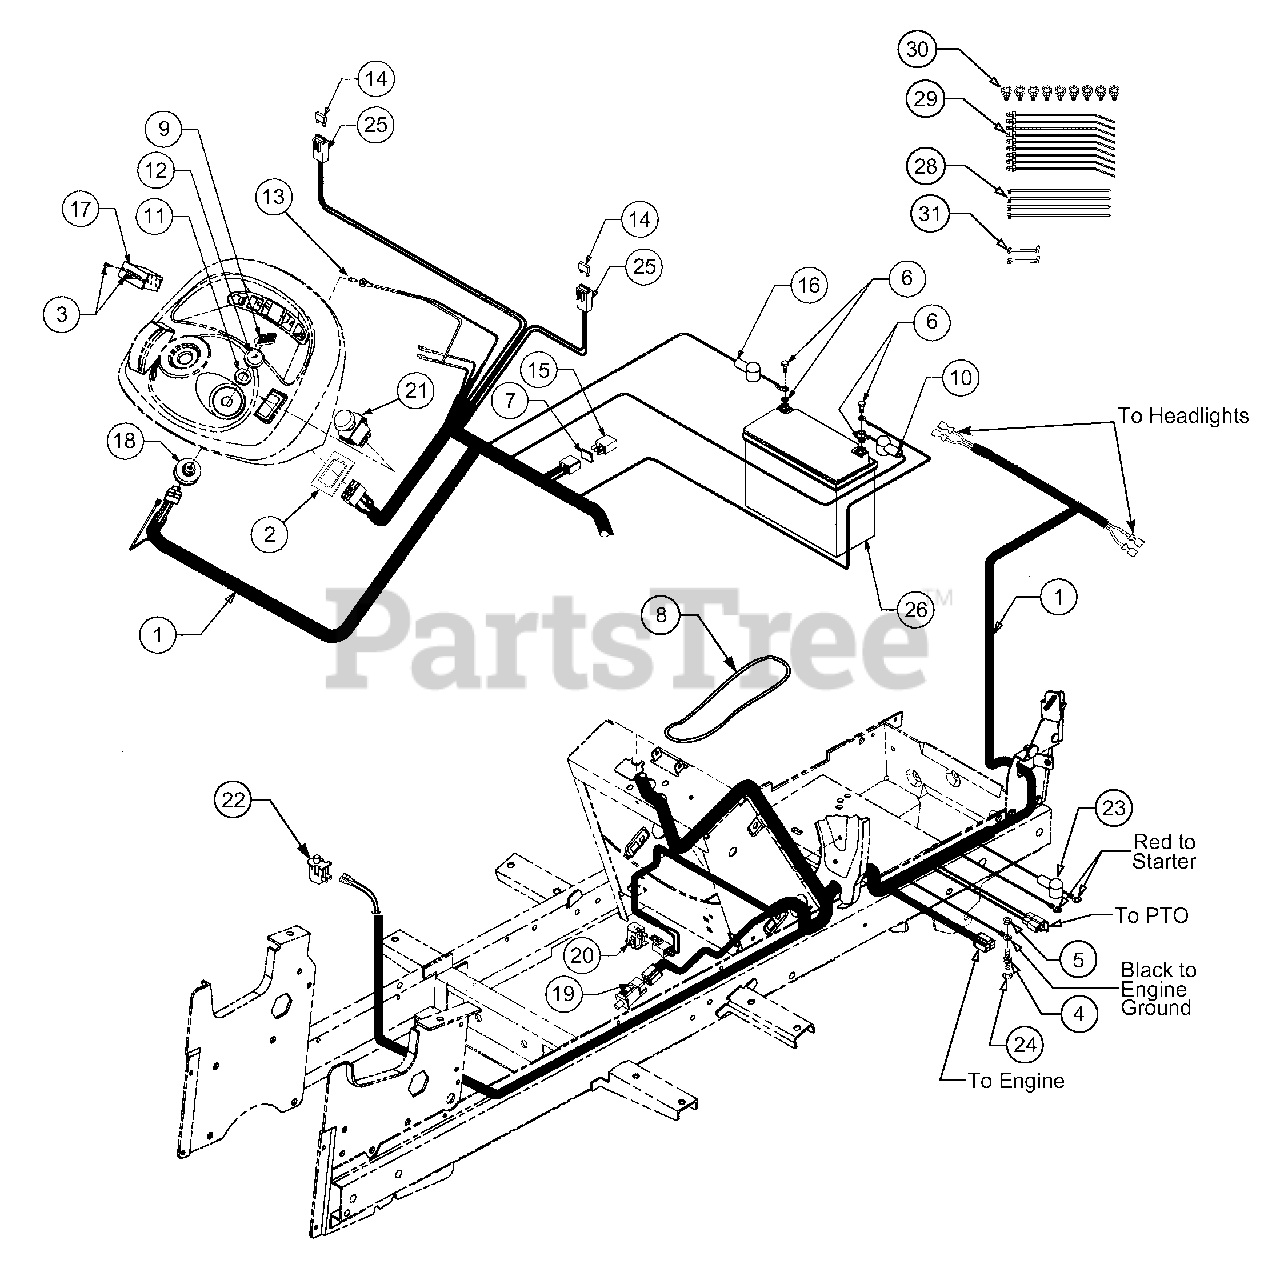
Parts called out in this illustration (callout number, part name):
1	Wire Harness, Main
2	Bracket, PTO Switch Retainer
3	Screw, Truss Hd Tapp, #6 x .62
4	Stud, Ground
5	Nut, Hex, 5/16-18 GR5
6	Battery Cable Hardware
7	Gasket, Silicone
8	Strap, Battery Retainer
9	Key, Ignition (Set of 2)
10	Cover, Terminal Black
11	Nut, Ignition Switch
12	Cap, Ignition Switch
13	Bulb, Indicator
14	Fuse, 25 Amp
15	Relay
16	Cover, Terminal Red
17	Hour Meter
18	Switch, Ignition
19	Switch, Interlock (Brake)
20	Switch, Snap Mount - Normally Closed
21	Switch, PTO
22	Switch, Snap Mount Seat
23	Cover, Terminal Red
24	Washer, External Lock, 5/16
25	Holder, Fuse w/Mounting Clip
26	Battery
28	Tie, Self-Clinch Cable
29	Tie, Pushmount
30	Clip, Cable
31	Clip, Wire
